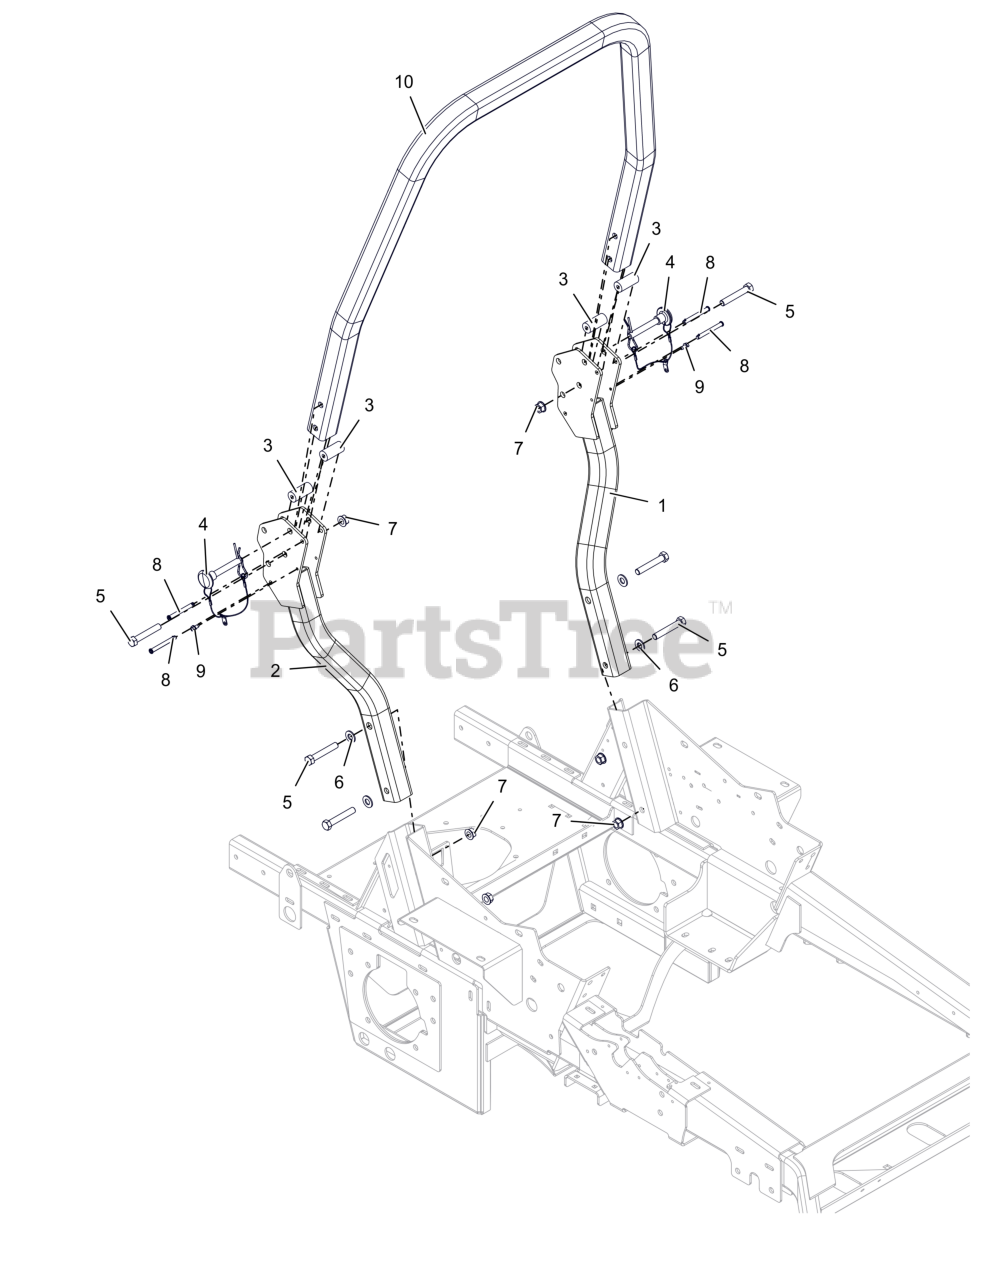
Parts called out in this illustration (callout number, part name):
1	WLDMT, LH ROPS MOUNTING W/ SAFETY DECAL
2	WLDMT, RH ROPS POST W/ SAFETY DECAL
3	BUMPER, ROPS ANTI-VIBRATION
4	PIN, ROPS W/LANYARD
5	BLT, HEX .50-13X3.00 G5 ZCC
6	WSHR,FLT .531X1.062X.095 ZCC
7	NUT-LK-CTR-FLG .500-13 GG ZCC
8	PIN, SLIC .312 X 2.570
9	SCR-TAP .25-20X.50 HWH ZCC
10	HOOP, ROPS
